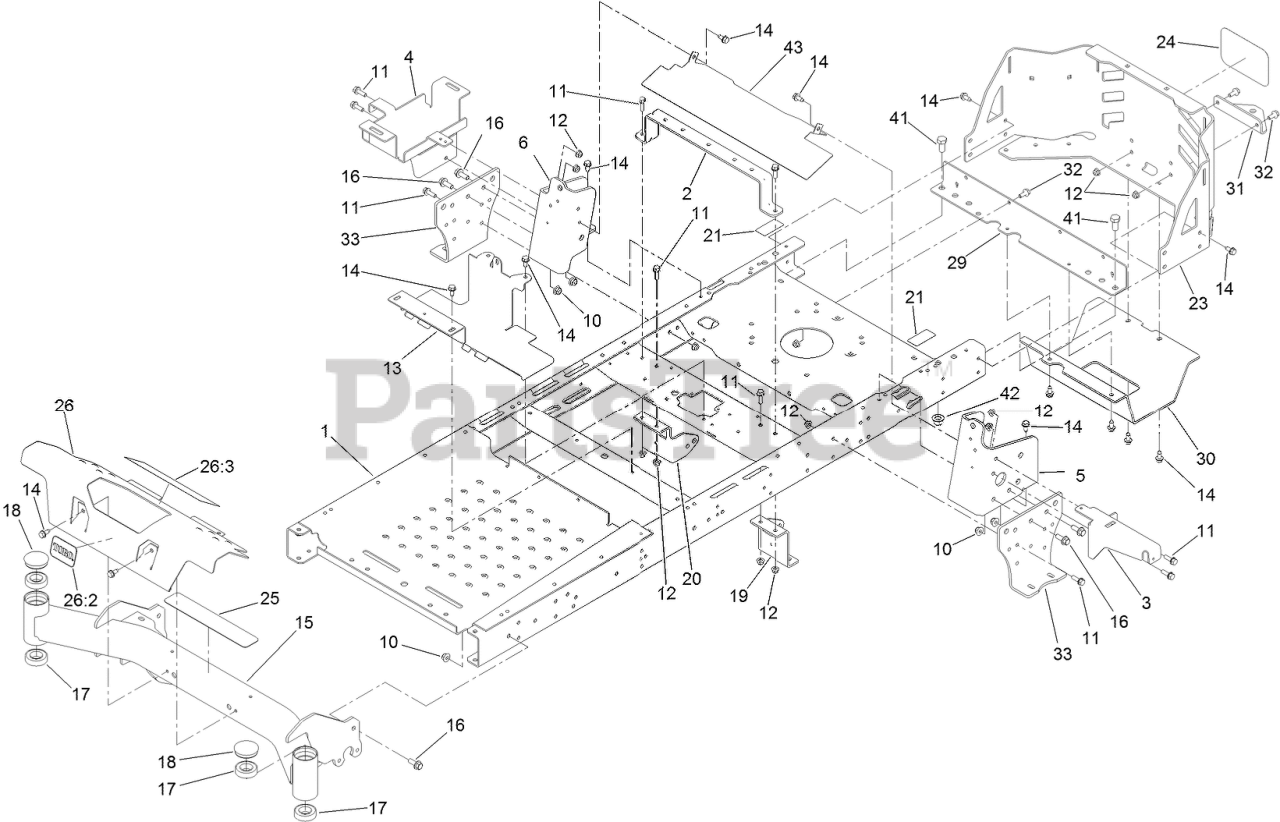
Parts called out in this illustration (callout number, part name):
1	FRAME ASM
2	BRACE-SEAT,REAR (WIDE)
3	BRACKET-POD SUPPORT, LH
4	TRAY-BATTERY
5	BRACKET-MOUNTING, LH
6	BRACKET-MOUNTING, RH
10	NUT-HF, NI
11	SCREW-HHF
12	NUT-HF, NI
13	BRACKET-MOUNT
14	SCREW-HWHTF
15	AXLE-FRONT
16	SCREW-HHF
17	BEARING-BALL
18	CAP-GREASE
19	MOUNT-HYDRO, FRONT (LH)
20	MOUNT-HYDRO, FRONT (RH)
21	DECAL-BYPASS
23	GUARD-ENGINE
24	DECAL
25	TREAD-STEP
26	FOOTREST
26:2	Decal
26:3	DECAL-DANGER
29	CROSSMEMBER-REAR
30	GUARD-MUFFLER
31	BRACKET-HITCH
32	SCREW-HHF
33	MOUNT-HYDRO
41	SCREW-HH
42	NUT-LOCK
